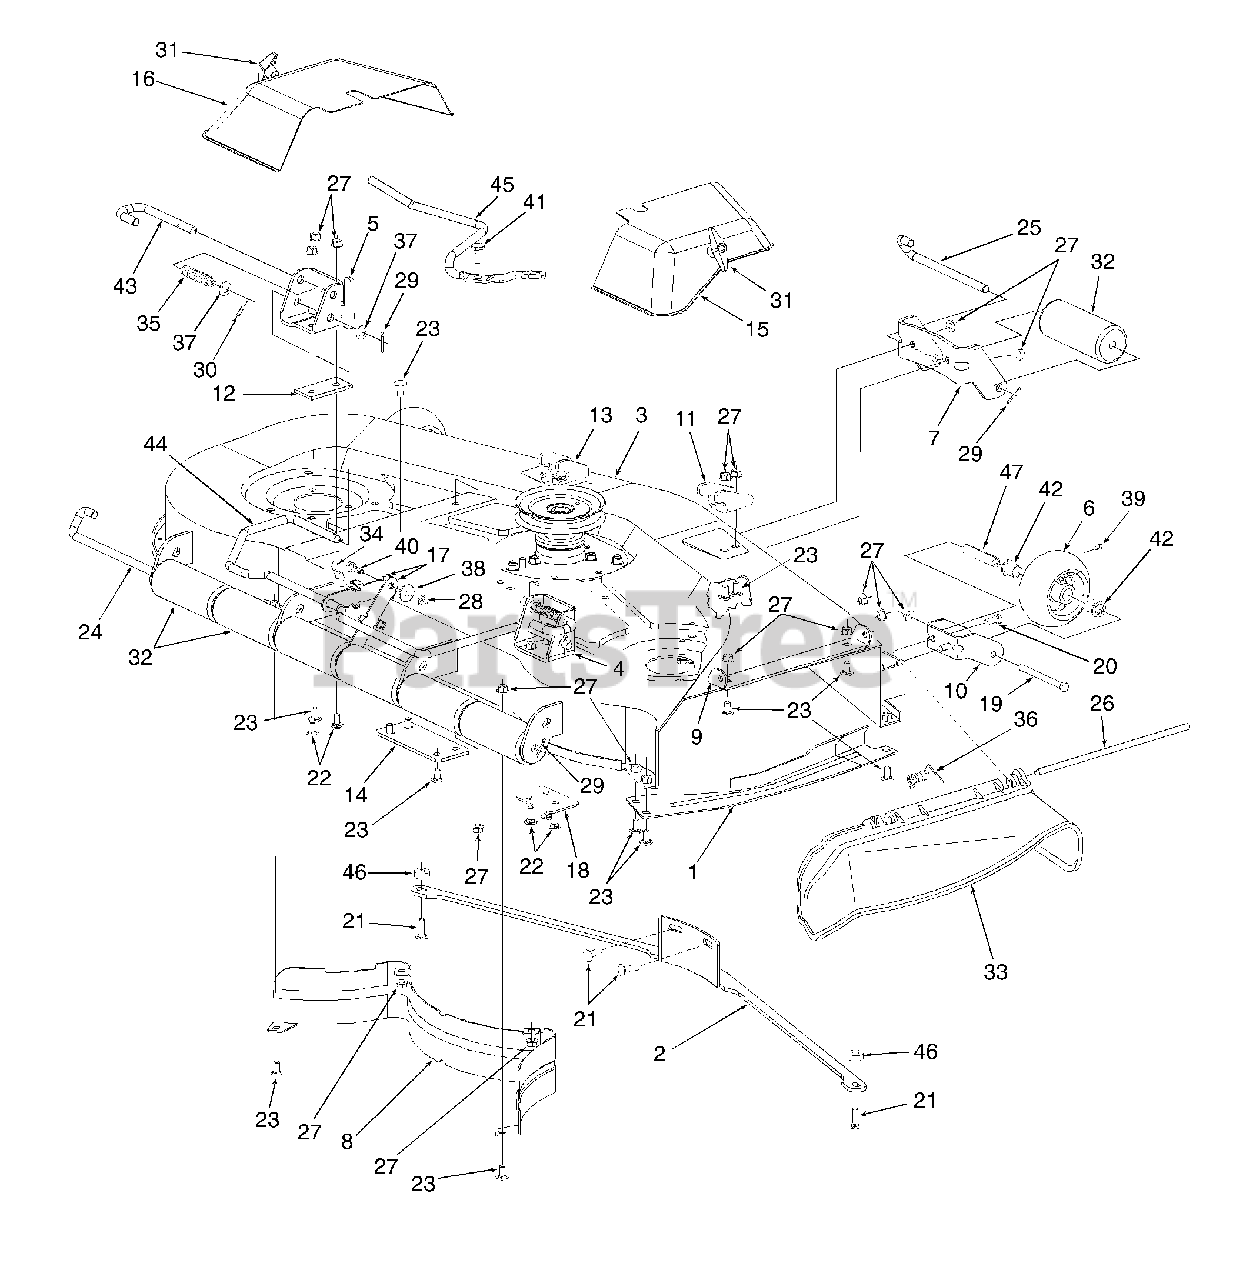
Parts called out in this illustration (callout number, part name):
1	Guard, Finger
4	Bracket, Rear Hanger RH
5	Bracket, Rear Hanger LH
6	Wheel Ass'y, 5" Deck
7	Bracket, Front Roller
10	Bracket, Deck Wheel
11	Bracket, Front Deck - RH
16	Cover, Belt - LH
17	Link, Deck Support
20	Screw, Hex Cap, 3/8-16 x .88 GR5
21	Bolt, Carriage, 3/8-16 x 1.25 GR5
22	Bolt, Carriage, 3/8-16 x 1.0 GR5
23	Bolt, Carriage, 3/8-16 x .75 GR5
25	Pin, Roller, 1/2 x 7.31
27	Nut, Hex Flange Lock, 3/8-16
28	Nut, Hex Flange Lock, 5/16-18
29	Pin, Cotter 1/8 x 1.0
30	Pin, Spirol Spring, 3/16 x 3/4
31	Knob, Wingnut, 5/16-18
32	Roller, Front & Rear
33	Deflector, Plastic Chute
34	Spring, Extension
35	Spring, Compression
36	Spring, Torsion
37	Washer, Flat, .536 x .93 x .05
38	Washer, Flat, .344 x 1.125 x .12
39	Grease Fitting
40	Bolt, Shoulder, .437 x .268:5/16-18
41	Bolt, Shoulder, .50 x .267:3/8-16
42	Bearing, Flange
43	Pin, Mower Support
44	Rod, Deck Support
45	Rod, Idler Spring Mtg
46	Spacer, .406 x 1.0 x .38
47	Spacer, Wheel
